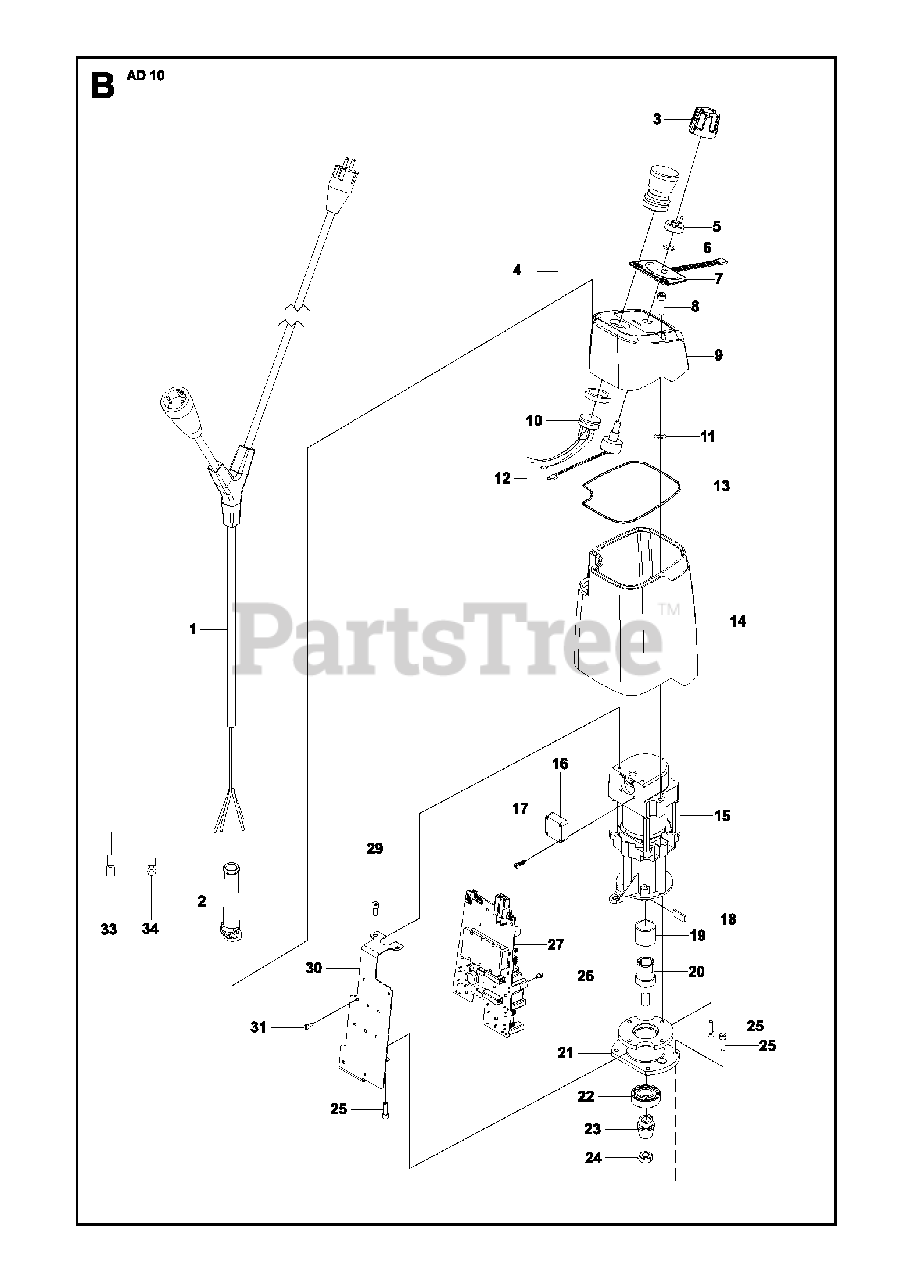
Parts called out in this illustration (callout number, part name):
1	CABLEY-cable AUS 230V
22	BALL BEARING
24	HEXAGON LOCKING NUT
27	PRINTED CIRCUIT ASSY230 V
27	PRINTED CIRCUIT ASSY110 V
